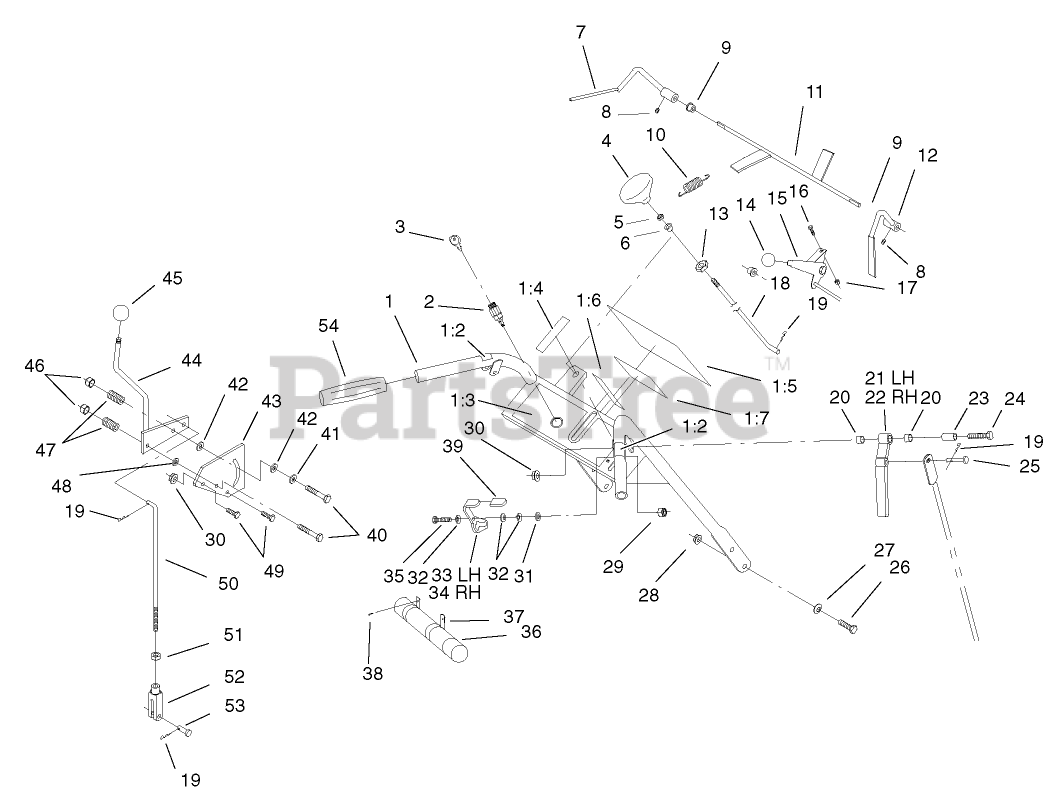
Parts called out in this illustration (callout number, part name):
1	HANDLE ASM
1:2	DECAL-LOCK, NEUTRAL
1:3	DECAL-WARNING
1:4	DECAL-THROTTLE
1:5	DECAL-PROLINE
1:6	DECAL-ENGAGE, DECK
1:7	DECAL-CAUTION, BRAKE
2	SWITCH & KEY (INCLUDES NUT & WASHER)
3	KEY-IGNITION
4	Knob-Push / Pull
5	NUT-JAM
6	Bearing-Nylon
7	LEVER-LH
8	SCREW-SET
9	BUSHING-NYLON
10	SPRING-EXTENSION
11	ROD-CONTROL, OPERATOR PRESENCE
12	LEVER-RH
13	NUT-PUSH
14	KNOB-BALL
15	THROTTLE CABLE ASM
16	BOLT-CARR
17	NUT-LOCK, NI
18	Linkage-Blade
19	PIN-COTTER
20	BUSHING-SLEEVE
21	LH Drive Lever ASM
22	RH Drive Lever ASM
23	Bushing-Lever, Drive
24	SCREW-HH
25	Pin-Clevis
26	SCREW-HH
27	WASHER-BELLEVILLE
28	NUT-HHF, WHIZ
29	NUT-LOCK, NI
30	NUT-HF
31	WASHER-FLAT
32	WASHER-SPRING
33	LATCH-LEVER, LH DRIVE
34	LATCH-LEVER, RH DRIVE
35	SCREW-HH
36	TUBE-MANUAL
37	CLAMP-R
38	SCREW-HWHTF
39	GRIP-LATCH
40	SCREW-HH
41	Washer-Friction
42	Washer-Friction
43	PLATE-LEVER, SHIFTER
44	LEVER-SHIFT
45	KNOB-BALL
46	NUT-LOCK, NI
47	SPRING-COMPRESSION
48	WASHER-PLAIN
49	SCREW-HH
50	Rod-Control, Speed
51	NUT-JAM
52	YOKE-ADJUSTABLE
53	PIN-CLEVIS
54	Grip-Handle
